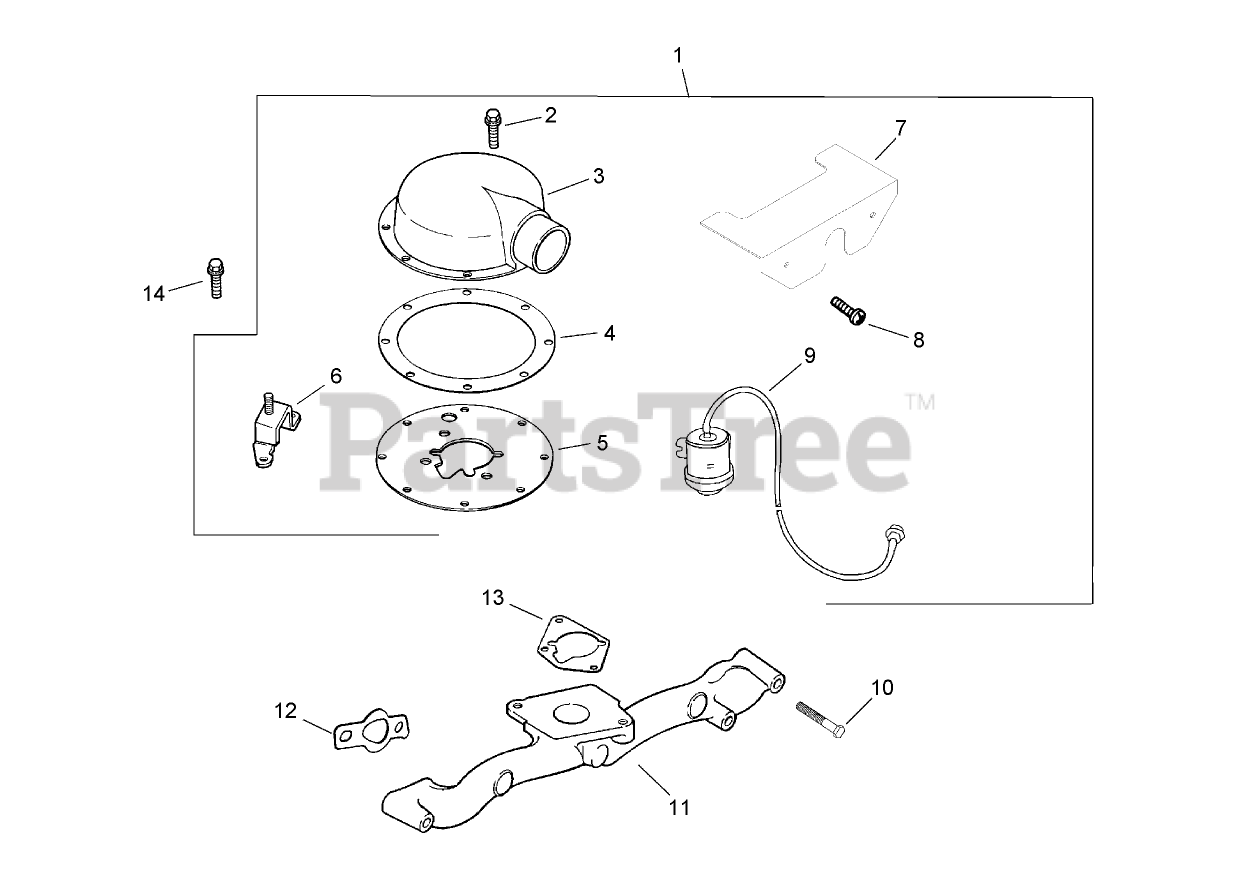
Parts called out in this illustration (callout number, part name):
1	Heavy Duty Air Cleaner Kit (Includes 2-9, 24 853 77-S, & 24 113 97-S)
2	SCREW-FLANGE, THREAD FORMING (M6X1.0X16)
3	Adapter-Intake, Air
4	Gasket-Adapter, Air Cleaner
5	Plate-Adapter
6	Bracket-Base, Air Cleaner
7	Shield-Debris
8	SCREW-PPH (11-16X3/4)
9	Air Filter Gauge Kit
10	Screw-HF (M6x1.0x55)
11	Manifold-Intake
12	Gasket-Manifold, Intake
13	GASKET-BASE, AIR CLEANER
14	Screw-HF (M6x1.0x16)
